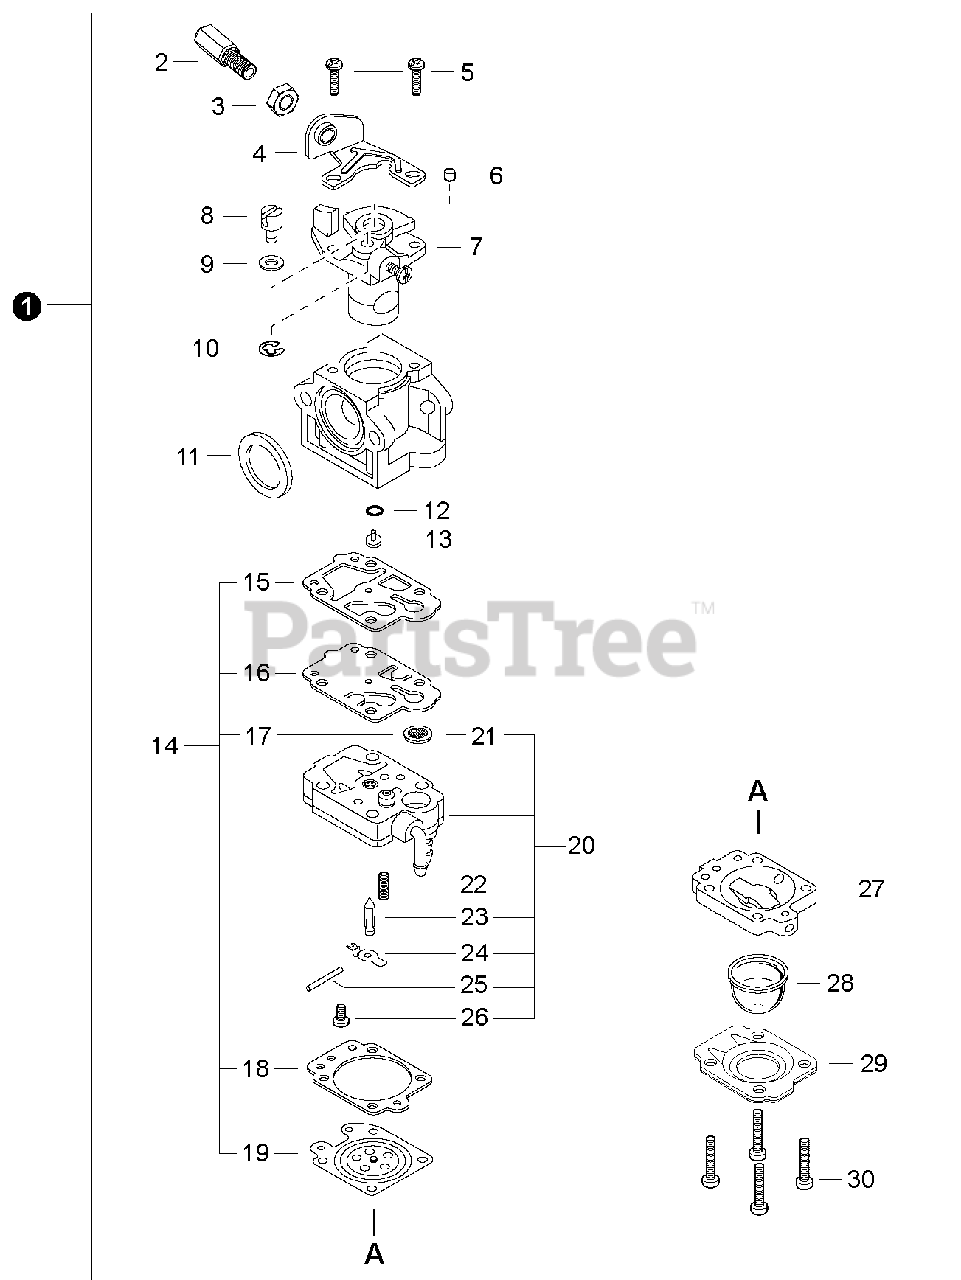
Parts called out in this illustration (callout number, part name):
1	CARBURETOR WYJ-396
2	NUT, CABLE ADJUST
3	NUT - 7
4	BRACKET, THROTTLE CABLE
5	SCREW
6	CAP, LIMITER
7	THROTTLE VALVE ASSY
8	SWIVEL
9	WASHER
10	RING, RETAINING
11	SEAL
12	O-RING
13	JET, MAIN
14	DIAPHRAGM/GASKET KIT
15	GASKET, PUMP
16	DIAPHRAGM, PUMP
17	STRAINER
18	GASKET, METERING
19	DIAPHRAGM, METERING
20	PUMP BODY ASSY
21	STRAINER
22	SPRING, METERING LEVER
23	VALVE, INLET NEEDLE
24	LEVER, METERING
25	PIN, METERING LEVER
26	SCREW, METERING LEVER PIN
27	PURGE BASE ASSY
28	BULB, PURGE
29	RETAINER, PURGE BULB
30	SCREW, PUMP COVER
